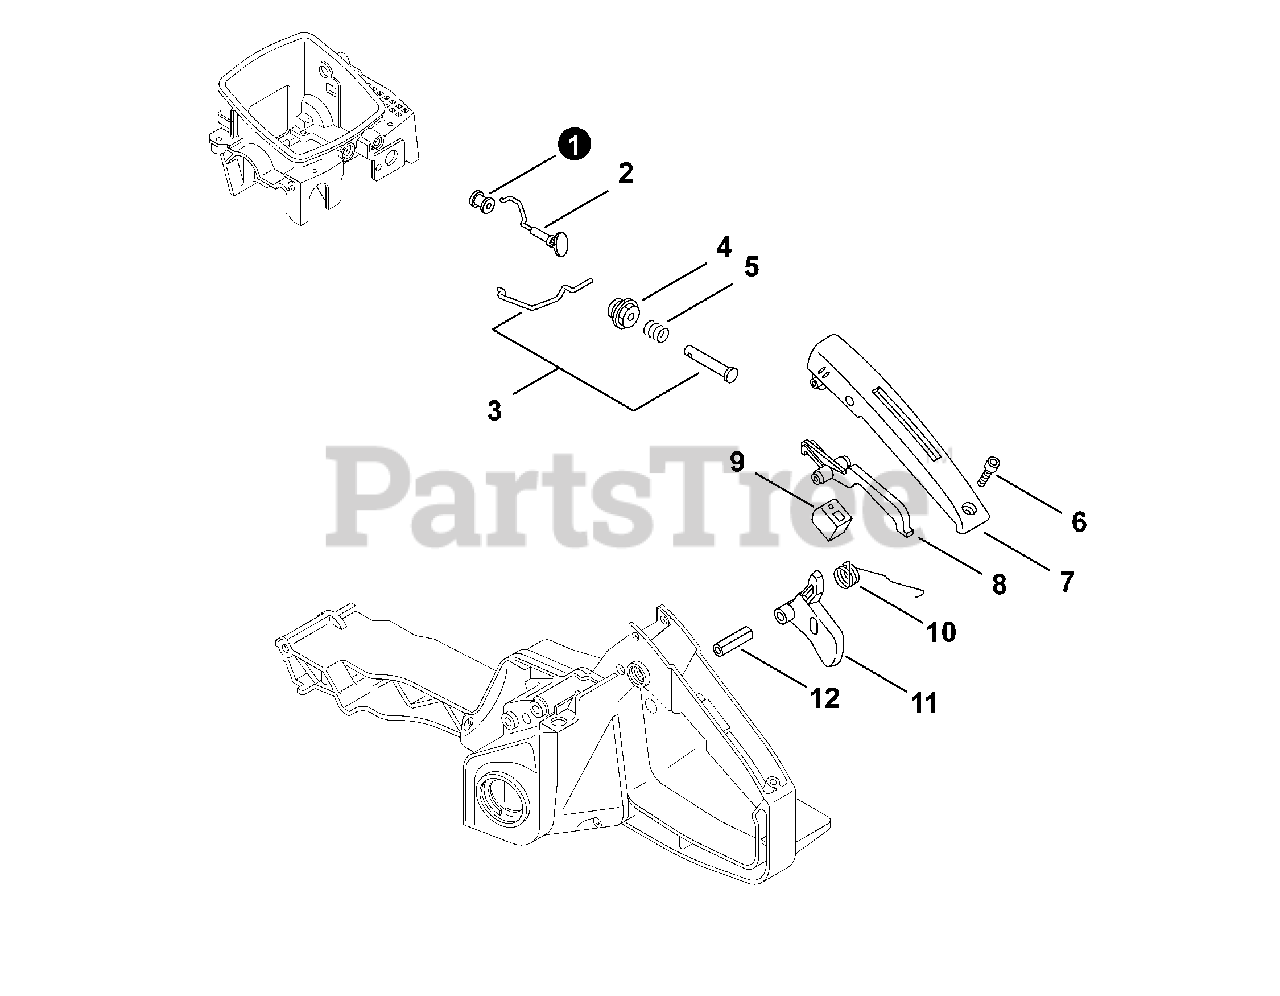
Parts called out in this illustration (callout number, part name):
1	GROMMET, CHOKE
2	ROD, CHOKE
3	THROTTLE ROD KIT
4	GROMMET, THROTTLE ROD
6	BOLT 4×14
7	COVER, HANDLE
8	LEVER, THROTTLE LOCKOUT
9	CUSHION, THROTTLE
10	SPRING, THROTTLE RETURN
11	TRIGGER, THROTTLE
12	PIN, SPRING Ø5×25 MM
